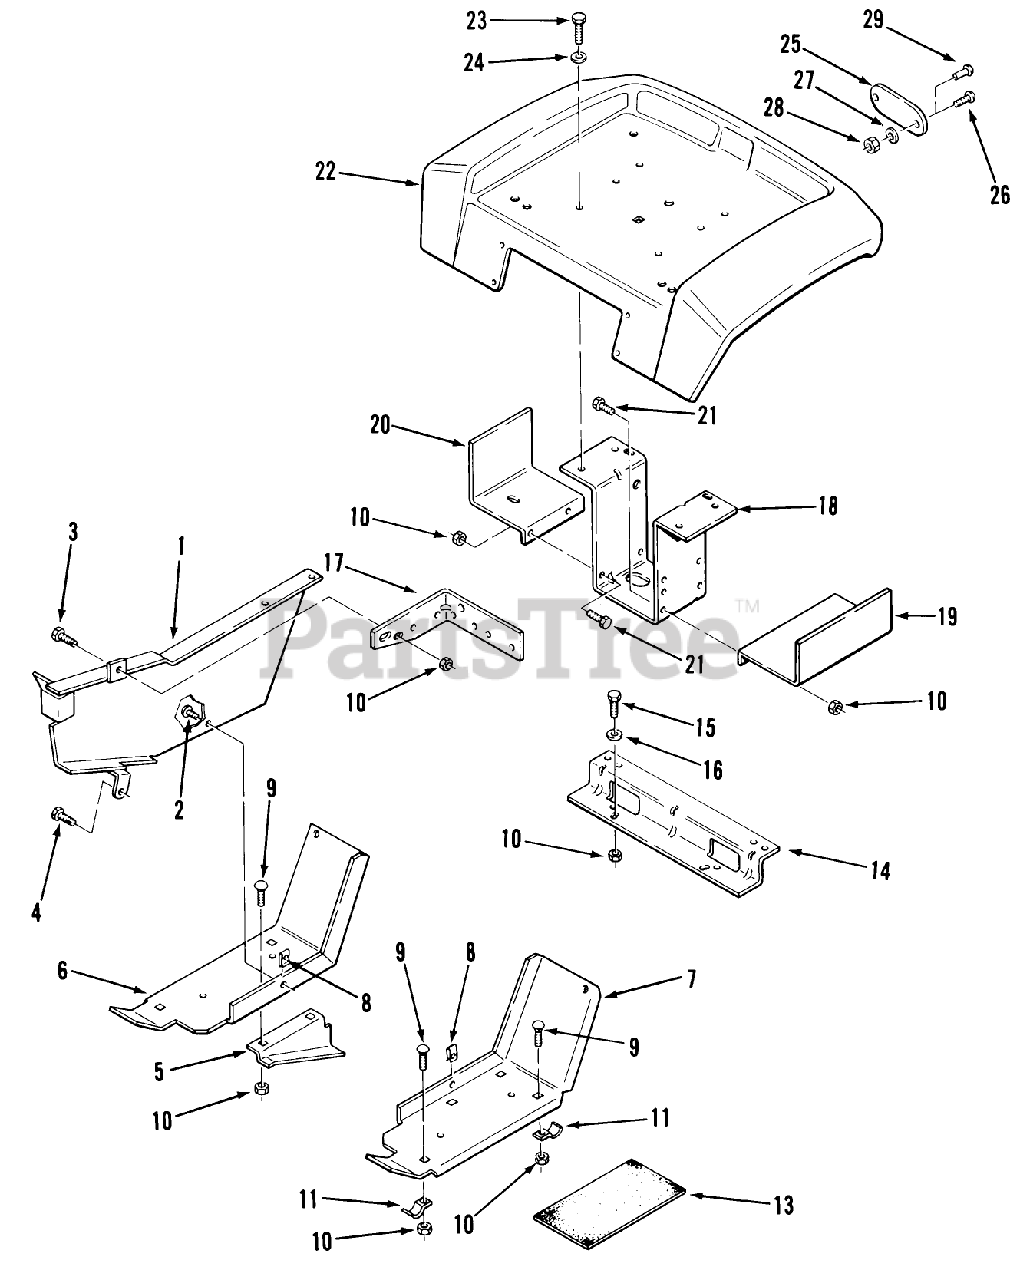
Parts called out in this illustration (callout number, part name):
4	SCREW
9	CARRIAGE BOLT -4
11	BRACKET
13	PAD-FOOTREST
16	WASHER 5/16 SAE
17	BRACKET-BELT*B
23	S.T. Bolt 5/16-18 x 5/8
24	WASHER 5/16 SAE
